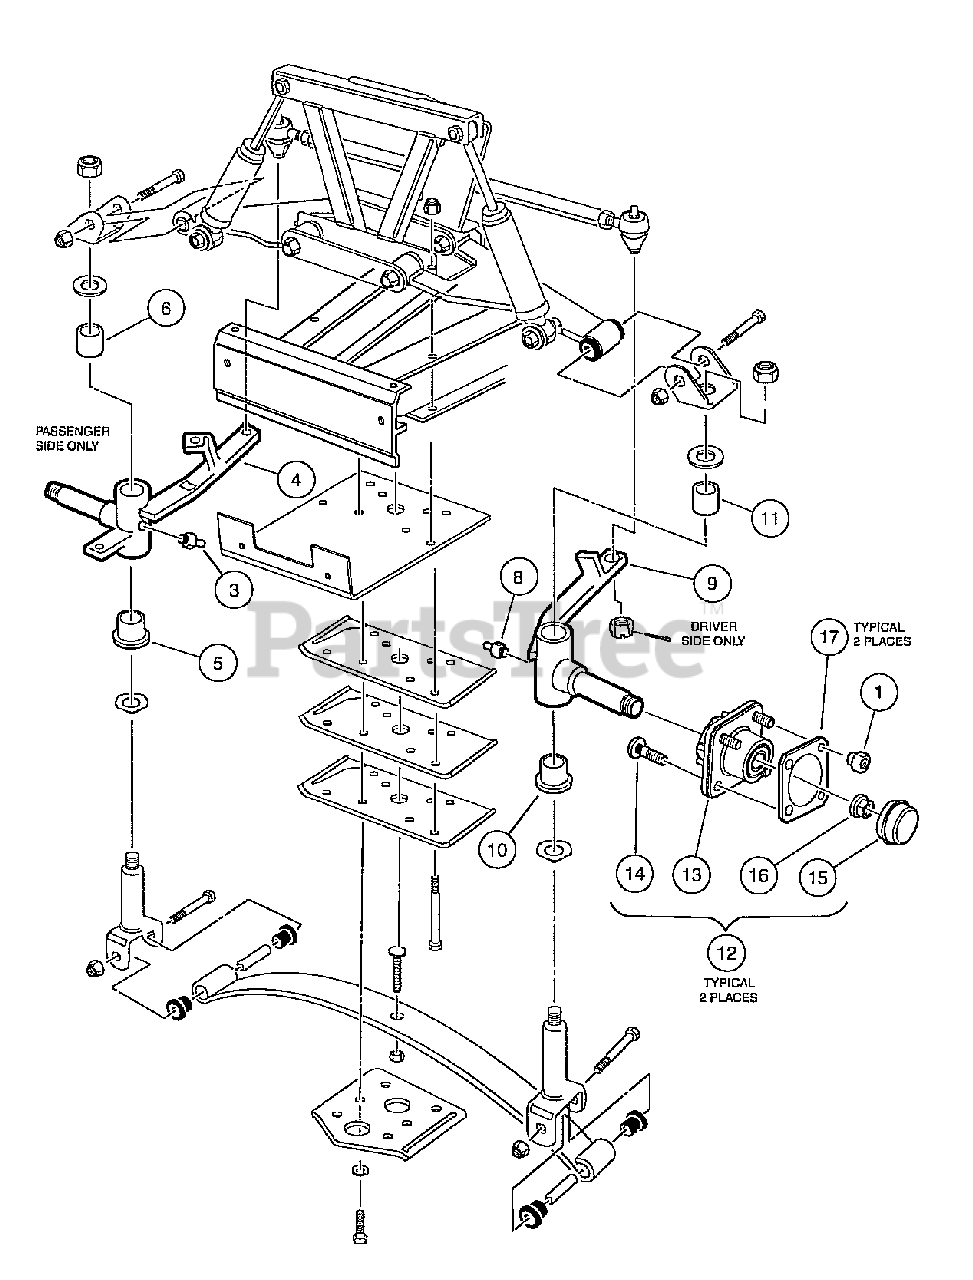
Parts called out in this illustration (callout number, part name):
1	Nut, 1/2-20 Lug
2	Assembly, Spindle, Right Hand
3	Fitting, 1/4-28 Thread-Forming Grease
4	Sub-Assembly, Spindle, Right-Hand
5	Bushing, Flanged Bronze
6	Bushing, Bronze Spindle
7	Assembly, Spindle, Left-Hand
8	Fitting, 1/4-28 Thread-Forming Grease
9	Sub-Assembly, Spindle, Let Hand
10	Bushing, Flanged Bronze
11	Bushing, Bronze Spindle
12	Replacement Kit, Front Hub
13	Front Hub Assembly, Ball Bearing
14	Lug Stud, 1/2-20 UNF, 4037 Stl
15	Cap, Front Hub
16	Hex Nut, Locking Flange, M14x2
17	Plate, Wheel Spacer
